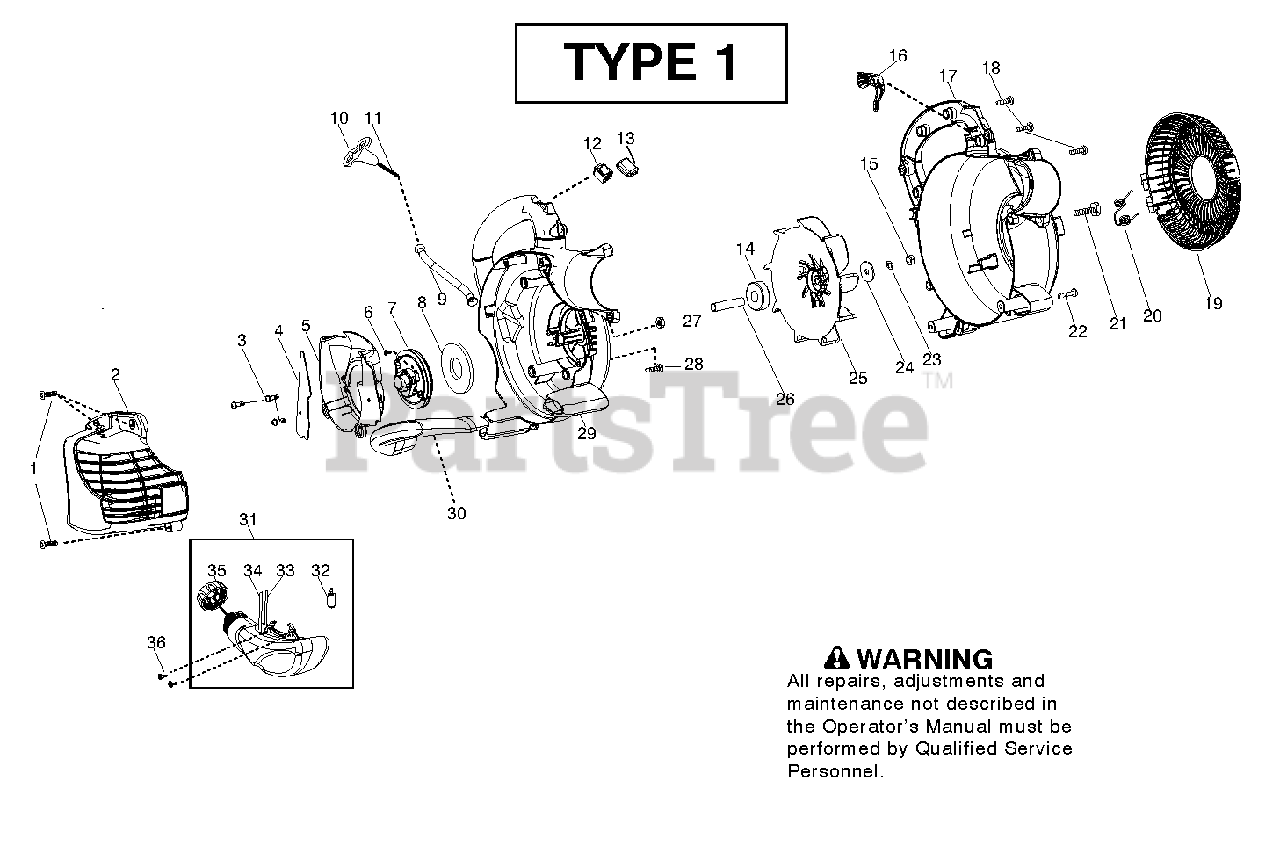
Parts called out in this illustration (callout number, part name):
2	ASSY COVER ENGINE
4	SHIELD BAFFLE
6	SCREW SEMS TOOTHED WASHER
7	KIT STARTER PULLEY
8	KIT STARTER SPRING
9	TUBE STARTER ROPE
10	HANDLE STARTER BLK
12	KIT SWITCH
13	PROTECTOR, SWITCH
16	TRIGGER THROTTLE RED
17	COVER
19	DOOR VAC BLACK
20	SPRING VAC DOOR
22	SCREW #10 PLASTITE 1.362
24	WASHER, IMPELLER
25	ASSY IMPELLAR HUB
26	SPACER FLYWHEEL
29	ASSY SCROLL RIGHT
30	HANDLE VAC BLACK
31	Fuel Tank Assembly, Non Low Perm St
32	FUEL PICK-UP ASSY
35	ASSY FUEL CAP W/RETAINER
36	SCREW FUEL TANK RETAINER
